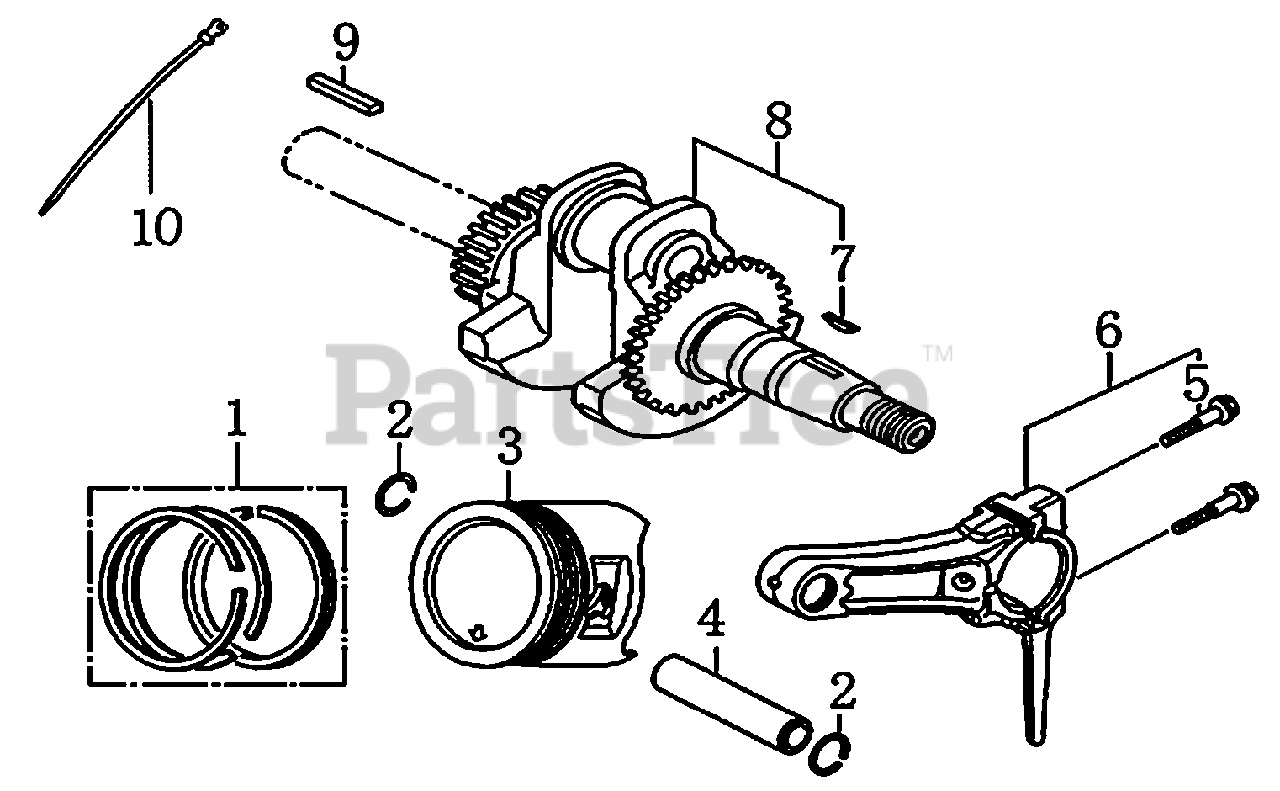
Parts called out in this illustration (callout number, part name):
2	CLIP, PISTON PIN
4	PIN, PISTON
5	BOLT, CONNECTING ROD
6	ROD ASSY., CONNECTING
8	CRANKSHAFT COMP
10	TIE WRAP
